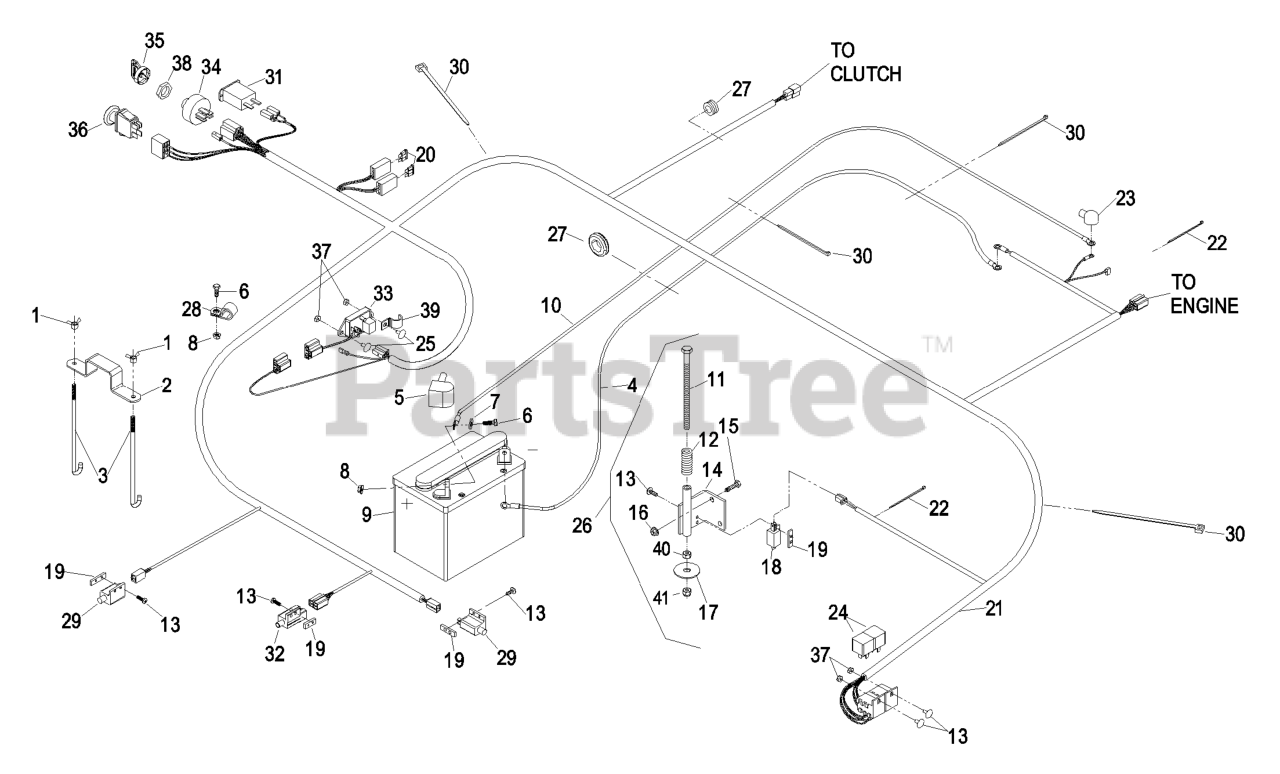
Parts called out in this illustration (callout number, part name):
1	WINGNUT
2	STRAP-HOLDDOWN
3	BOLT-HOLDDOWN
4	CABLE-GROUND, NEGATIVE
6	SCREW-HH
7	WASHER-FLAT
11	SCREW-HH
12	SPRING-SWITCH, SEAT
13	SCREW-PPH
14	BRACKET-SWITCH, SEAT
15	SCREW-HH
18	SWITCH-CLOSED, NORMALLY
19	PLATE-TAPPED
20	FUSE-BLADE TYPE, 20 AMP
21	HARNESS,WIRE LHP KC
22	TIE-CABLE
23	INSULATOR-SOLENOID
25	SCREW-HEAD, TRUSS
26	ASM,SEAT SWITCH ACTUATOR
27	GROMMET
28	CLIP-LOOM
29	SWITCH-OPEN, NORMALLY
30	TIE-PLASTIC
31	METER-HOUR
33	MODULE-DELAY, SEAT
35	KEY-IGNITION
36	SWITCH-PTO
37	NUT-LOCK, NI
38	NUT-SWITCH, IGNITION
39	CLIP-HALF, LOOM
40	NUT-HEX
41	NUT-LOCK, NI
